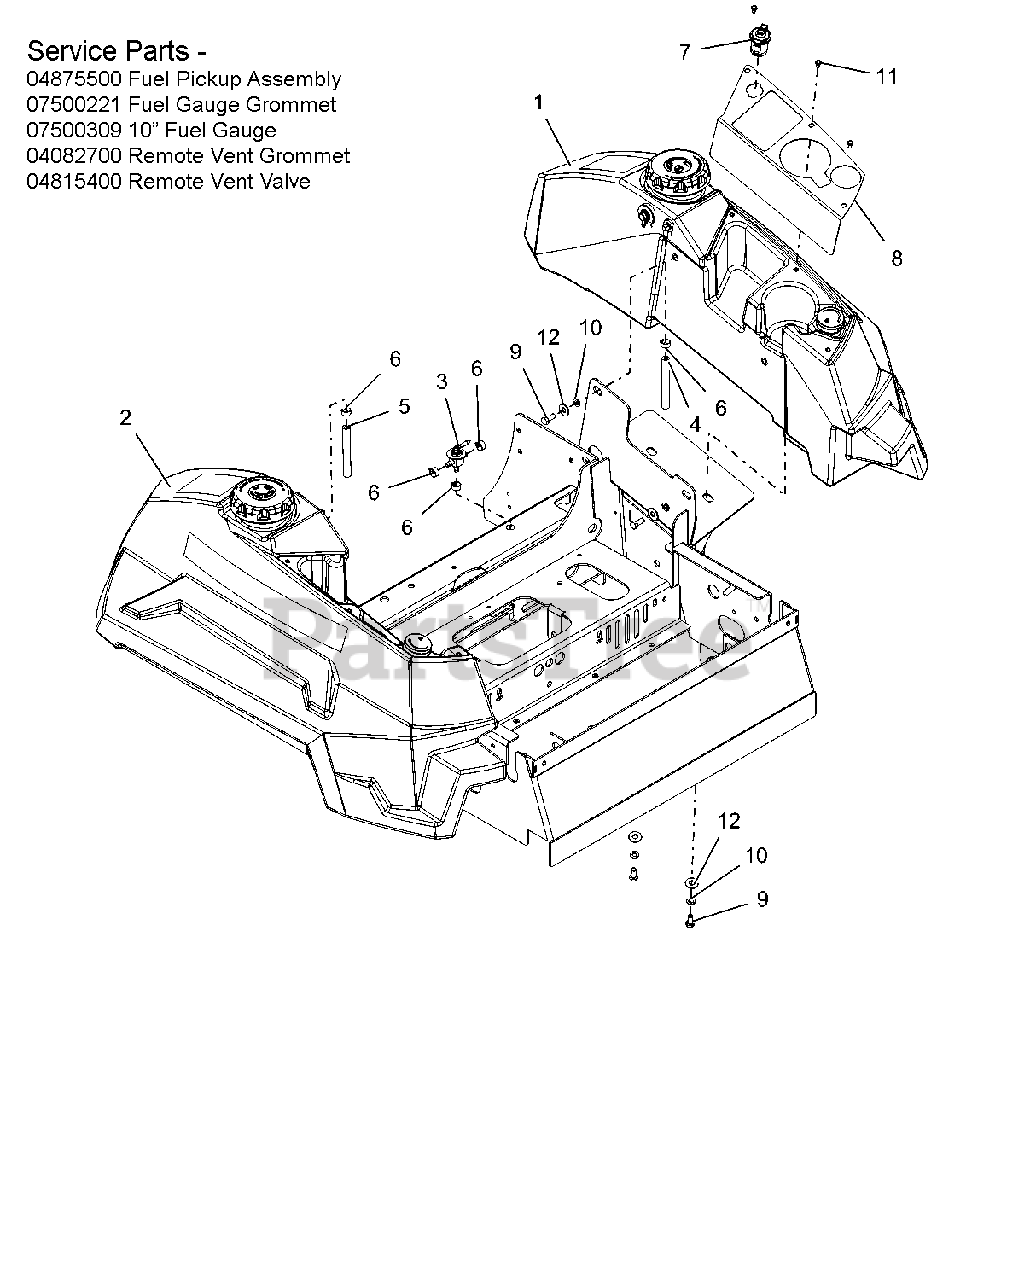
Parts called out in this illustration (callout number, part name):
1	ASSY-LH, PT400 FUEL TANK
1	10" FUEL GAUGE
1	REMOTE VENT GROMMET
1	REMOTE VENT VALVE
1	FUEL CAP
1	FUEL GAUGE GROMMET
1	FUEL PICKUP ASSEMBLY
2	ASSY-RH, PT400 FUEL TANK
2	FUEL CAP
2	FUEL GAUGE GROMMET
2	REOMOTE VENT GROMMET
2	REMOTGE VENT VALVE
2	10" FUEL GAUGE
2	FUEL PICKUP ASSEMBLY
3	VALVE, FUEL
4	.25 LOW-PERM GAS HOSE 19.00" LG - LH TANK TO VALVE
5	.25 LOW-PERM GAS HOSE 32.00" LG - LH TANK TO VALVE
6	CLAMP, FUEL LINE
7	PORT, 12 VOLT POWER
8	PLATE, CUP HOLDER (RED)
9	BLT-HEX .31-18X.75 GR5 YWZC
10	WSHR-LK .31X.078 REG YWZC
11	SCR-MCH 10-24X.38 HWHSTAINLESS
12	WSHR-FL-STL.38X.875X.083 YWZC
